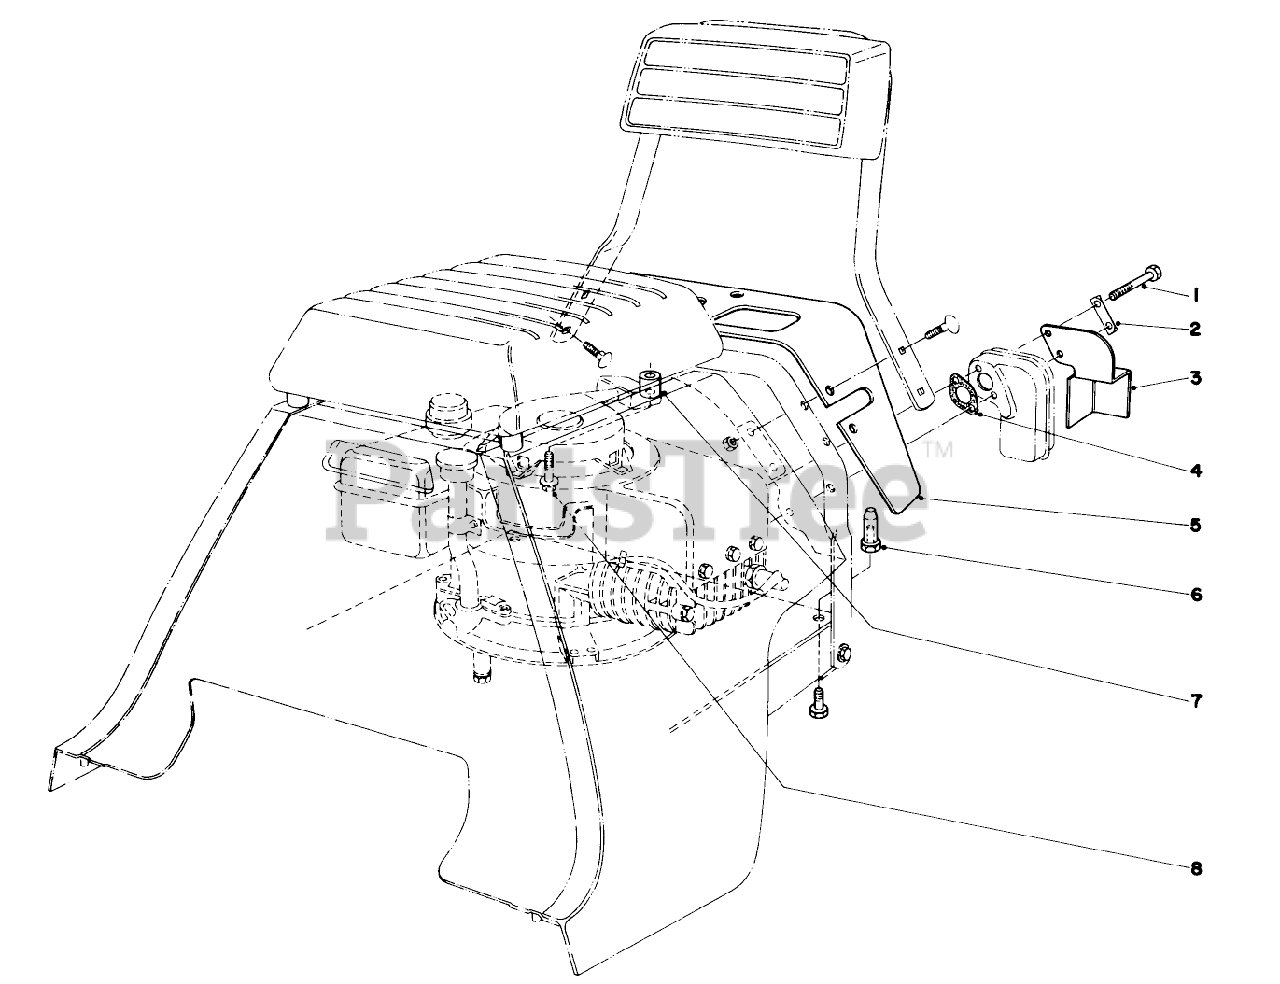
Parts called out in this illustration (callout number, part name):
1	SCREW-HH
2	Locking Plate
3	Deflector
4	Muffler Gasket
5	Extension Rear Body
6	PIN-MOUNTING, LOWER
7	Spacer
8	HEX FLANGE SCREW
